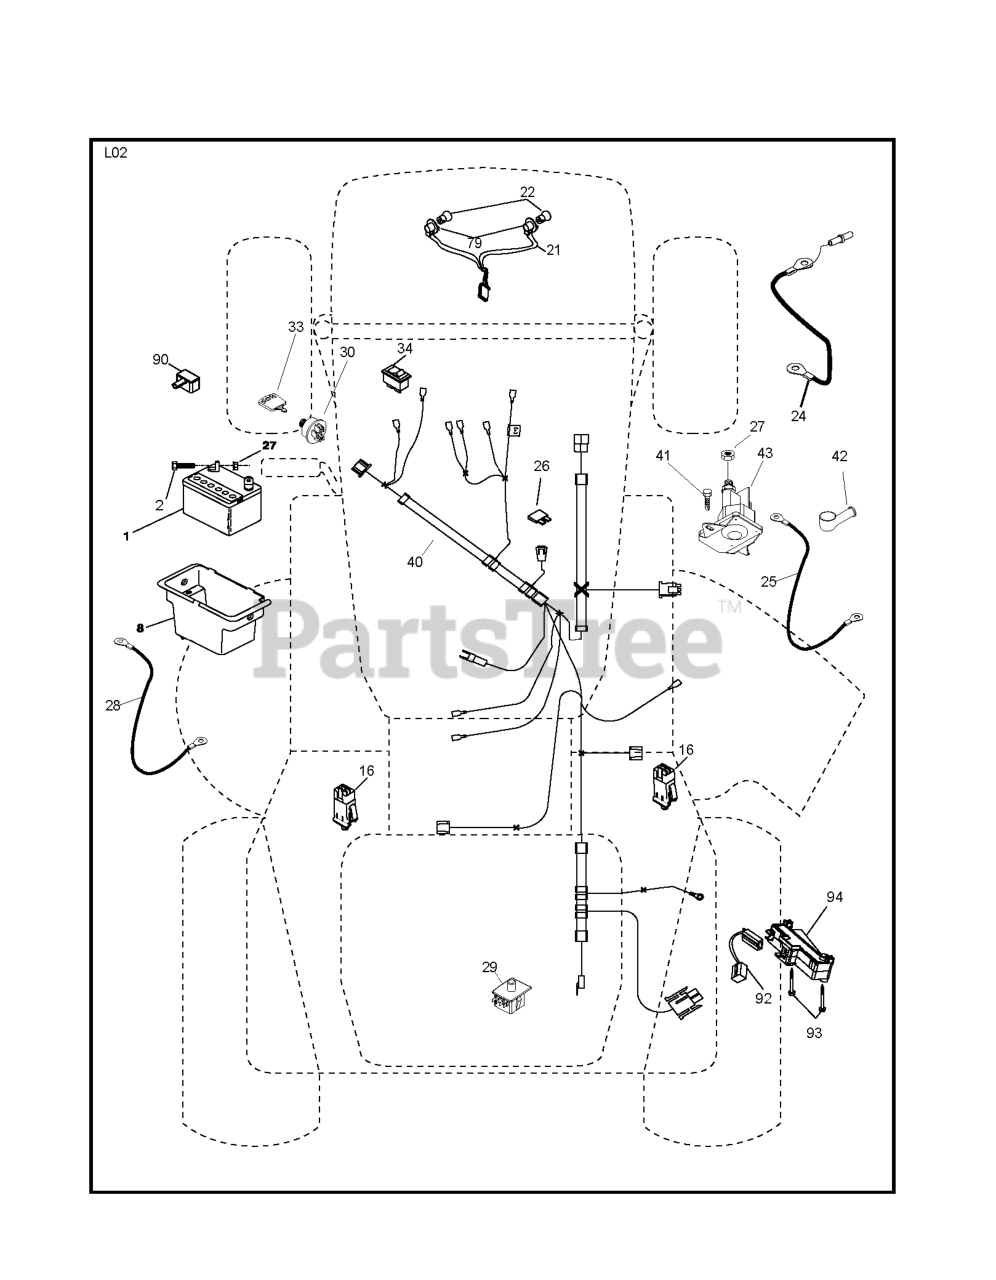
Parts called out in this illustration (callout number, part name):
1	Battery 12 Volt 25 Amp
2	BOLT.HEX.1/4.X.3/4.DICHROMATE
8	BOX.BATTERY.FENDER
16	SWITCH INTERLOOK PUSH-IN
21	HARNESS.W/LIGHT SOCKET
24	BATTERY CABLE GT
25	CABLE BATTERY
26	FUSE 20AMP
27	NUT
28	CABLE T
29	SWITCH.SEAT.DP W/RAMPS
30	SWITCH.IGN.DELTA.W.LGH.ROS
33	KEY.CHAIN.BLISTER.PACK.GEN.INT
40	HARNESS.IGN.CABLE.REG.
41	BOLT
42	TERMINAL COVER
43	SOLENOID.W/BRASS.PLUNGER
79	BULB HOLDER ASM.
90	COVER TERMINAL
92	HARNESS.PIGTAIL.CONSLE
93	SCREW.PLASTITE
94	MODULE.REVERSE.ROS
